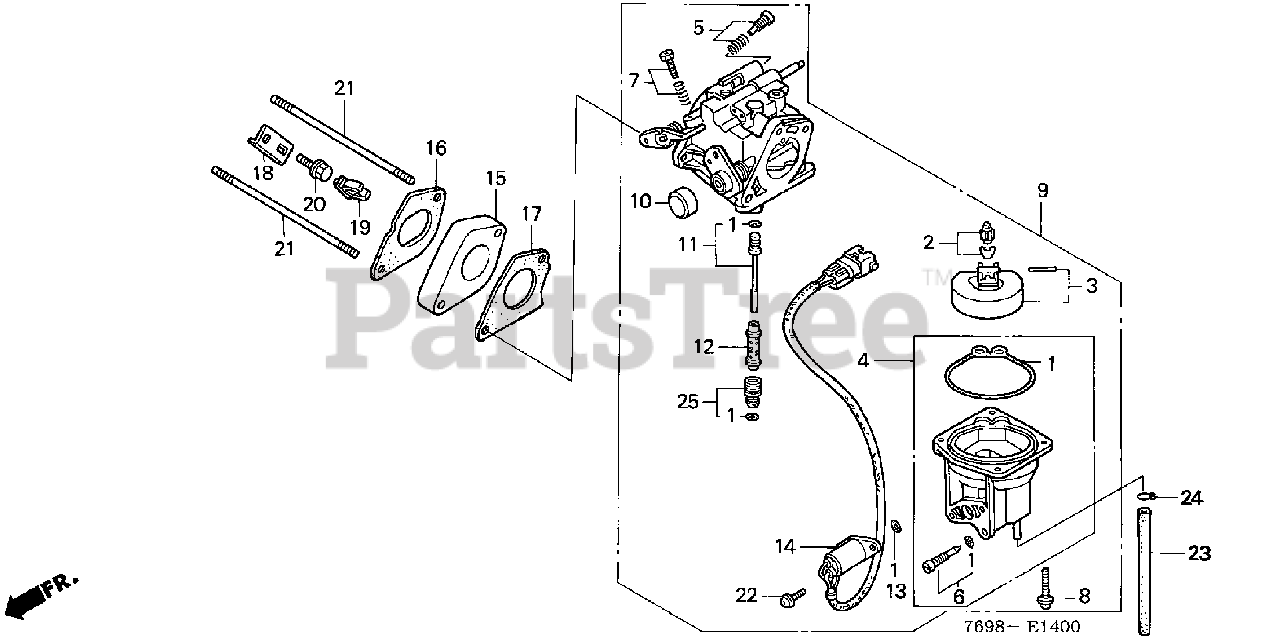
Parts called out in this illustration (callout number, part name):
1	GASKET SET
2	VALVE SET, FLOAT
4	CHAMBER SET, FLOAT
6	SCREW SET, DRAIN
8	SCREW-WASHER
9	CARBURETOR ASSY.
10	CAP, CHOKE LEVER DUST
11	JET SET (#48)
12	NOZZLE, MAIN
13	O-RING (5.8X1.9)
14	VALVE ASSY., SOLENOID
15	INSULATOR, CARBURETOR
16	GASKET, INSULATOR
17	GASKET, CARBURETOR
18	BRACKET, HARNESS CLIP
19	CLIP B, AIR TEMPERATURE SWITCH WIRE
20	BOLT, FLANGE (6X14)
21	BOLT, STUD (6X113)
22	SCREW-WASHER (5X12)
23	BULK HOSE, FUEL (4.5X3000) (4.5X380)
24	CLIP, TUBE (B8)
25	JET SET, MAIN (#92)
25	JET SET, MAIN (#95)
25	JET SET, MAIN (#98)
